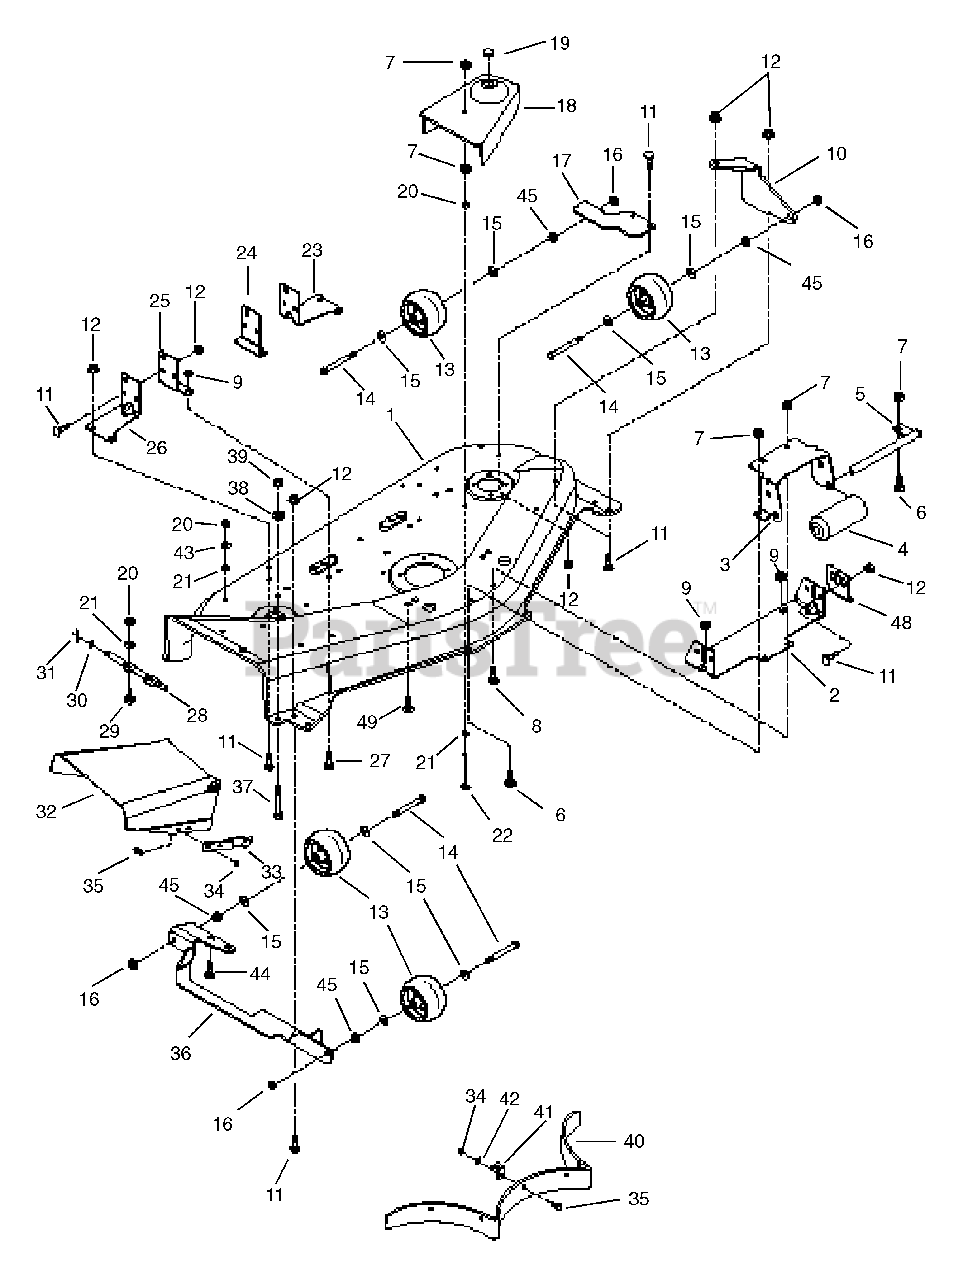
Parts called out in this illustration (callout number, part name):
1	Mower Pan Head w/Decals 48"
2	Front Hanger
3	Bracket-Roller
4	Roller
5	Roller Shaft
6	Bolt-Round Head Square Neck .31-18 x .75 Grade 5
7	Nut-Locking-Center .312-18
8	Bolt-Round Head Square Neck .312-18 x .62
9	Nut-Locking-Center .50-13 Grade 5
10	Bracket-Left Front
11	Bolt-Round Head Square Neck .31-18 x .75 Grade 5
12	Nut-Locking-Flange .312-18
13	Wheel 5 x 3
14	Bolt-Hex .50-13 x 4.50 Grade 5
15	Washer-Flat-Nylon .52 x 1.00 x .08
16	Nut-Locking-Center .50-13
17	Bracket-Left Rear
18	Cover-Right Hand Belt
18	Belt Cover Left Hand 48"
19	Button Plug 1.0
20	Nut-Hex .312-18
21	Washer-Lock .312 x .097
22	Bolt-Round Head Square Neck .31-18 x 3.25
23	Left Hand Rear Hanger
24	Left Hand Rear Hanger Support
25	Right Hand Rear Hanger Support
26	Right Hand Rear Hanger
27	Bolt-Hex .50-13 x 1 Grade 5
28	Hinge Pin
29	Bolt-Hex .31-18 x .75 Grade 5
30	Washer-Flat-Steel .406 x .812 x .065
31	Pin-Cotter .09 x .75
32	Chute Extension
33	Flat Spring
34	Nut-Locking-Center .250-20
35	Bolt-Round Head Square Neck .25-20 x .50
36	Mount-Roller
37	Bolt-Hex .38-16 x 2.50 Grade 5
38	Washer-Lock .375 x .115
39	Nut-Hex .375-16
40	Baffle
41	Baffle Tab
42	Washer-Flat-Steel .281 x .620 x .065
43	Washer-Flat-Steel .312 x .734 x .065
44	Bolt-Round Head Square Neck .312-18 x 1.00 Grade 5
45	Nut-Locking-Center .50-13
46	Guard-Foot-Left Hand
47	Guard-Foot-Right Hand
48	Mower Adjustment Tab
49	Bolt-Round Head Square Neck .50-13 x 1.00
